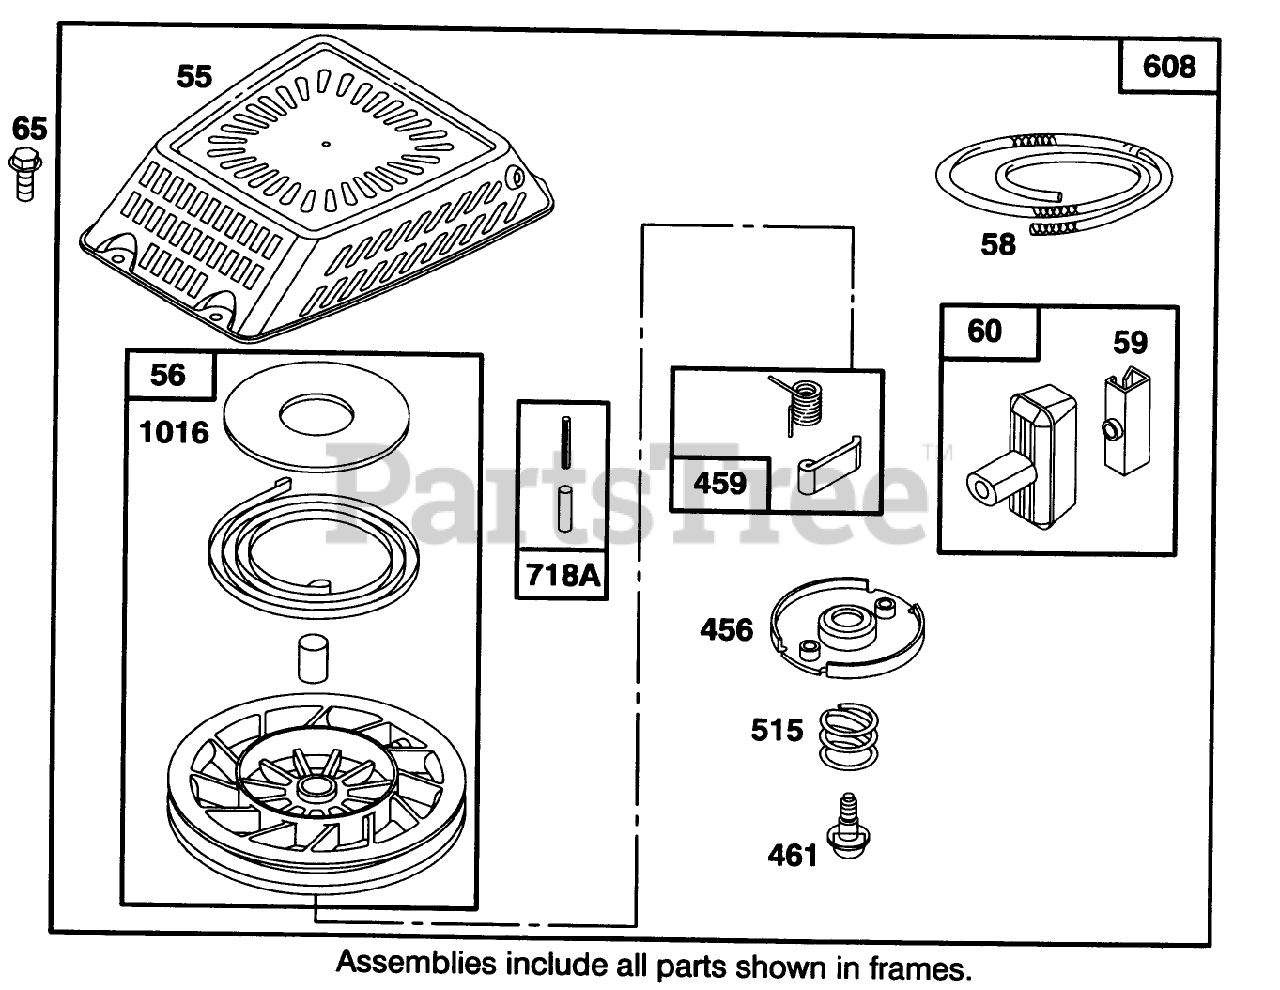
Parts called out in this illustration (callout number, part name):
60	HANDLE-REWIND STARTER
456	RETAINER - SPRING
515	SPRING - RETAINER
